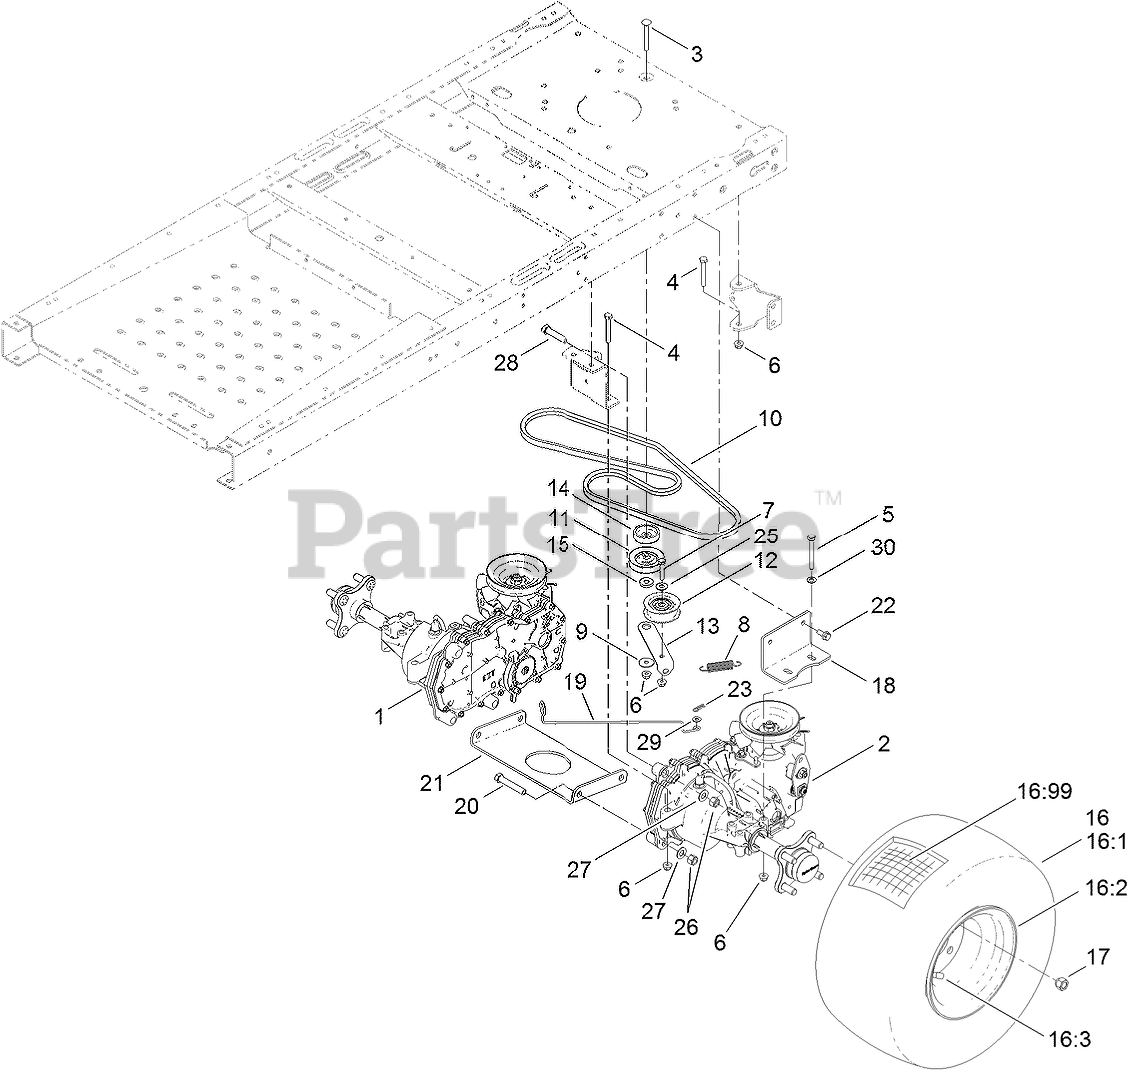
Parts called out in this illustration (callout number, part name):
1	RH HYDRO TRANSAXLE ASM
2	LH HYDRO TRANSAXLE ASM
3	SCREW-CARR
4	SCREW-HH
5	SCREW-HH
6	NUT-HF, NI
7	SCREW-HH
8	SPRING-RETURN, PEDAL
9	WASHER-PIVOT
10	V-BELT
11	PULLEY-IDLER
12	PULLEY-IDLER
13	ARM-IDLER
14	SPACER
15	SPACER-ARM, IDLER
16	4 PLY WHEEL AND TIRE ASM
16:1	TIRE-4 PLY
16:3	STEM-VALVE
17	NUT-LUG
18	MOUNT-HYDRO
19	ROD-BYPASS
20	SCREW-HH
21	PLATE-CROSS, HYDRO
22	SCREW-HHF
23	PIN-COTTER
25	WASHER-FLAT
26	NUT-LOCK, NI
27	WASHER-FLAT
28	SCREW-HH
29	WASHER-FLAT
30	WASHER-PLAIN
